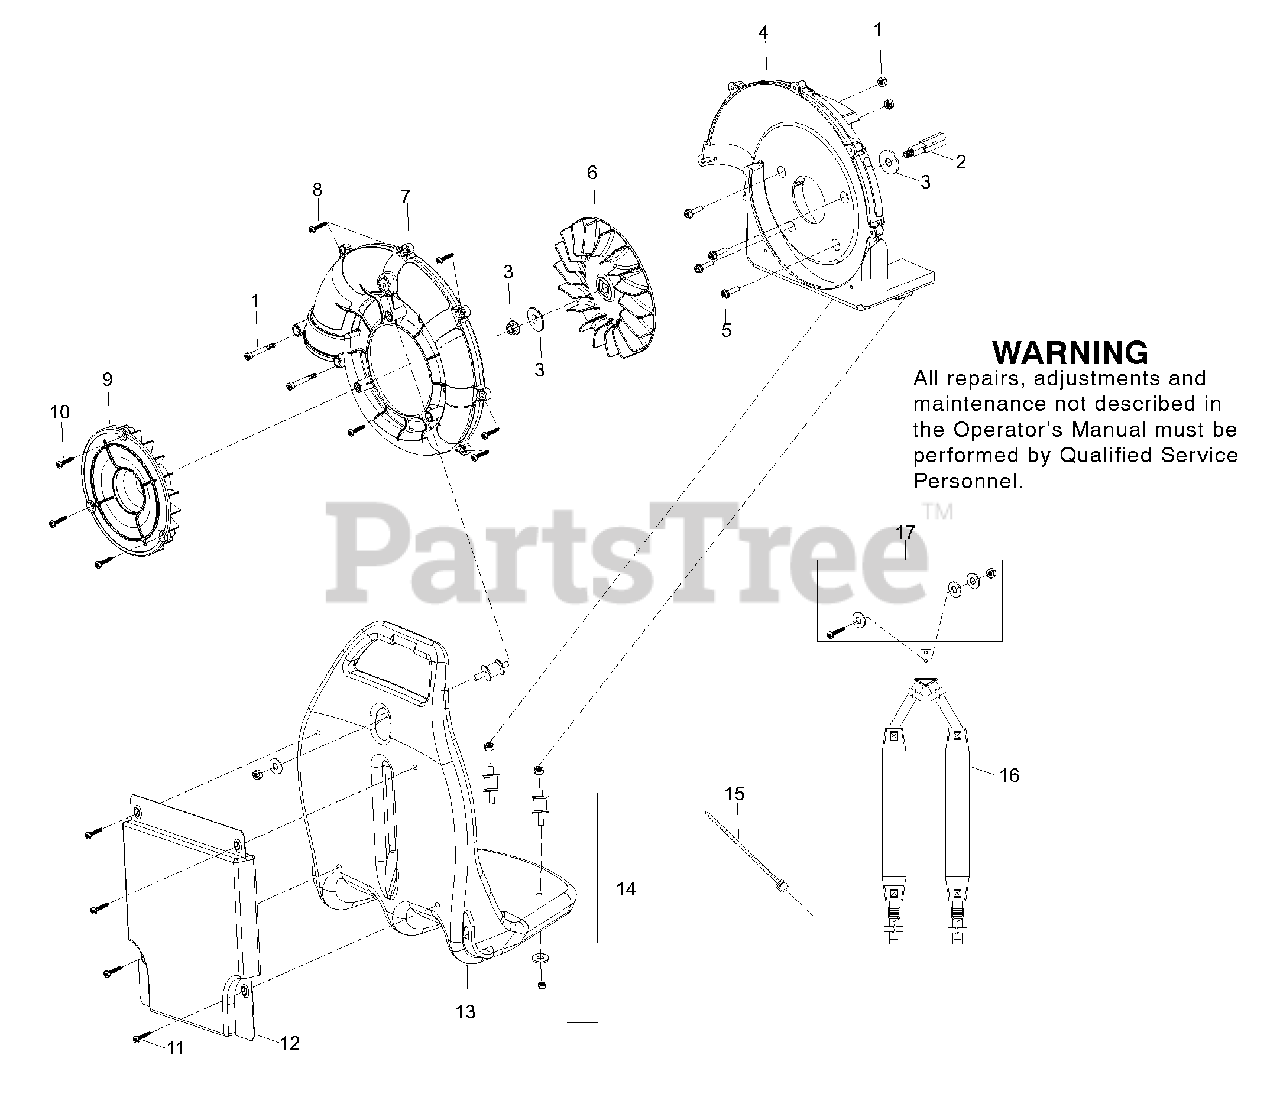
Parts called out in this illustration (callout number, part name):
1	Kit - Elbow Retention
2	Connect Axis
3	Kit - Impeller Washer & Nut
4	Front Screw Housing
5	Screw (4 pack) (9SRCBM05-30)
6	Impeller
7	Rear Screw Housing
8	Screw (6 pack) (9SKKBY8/16-0.75)
10	Screw (6 pack) (9SKKBB05-18)
11	Rivet - Ribbed (4 pack) (9RGB7.14-16.27)
12	Cushion Back
14	Kit - Isolator
15	Ligate Tape
17	Kit - Harness Hardware
